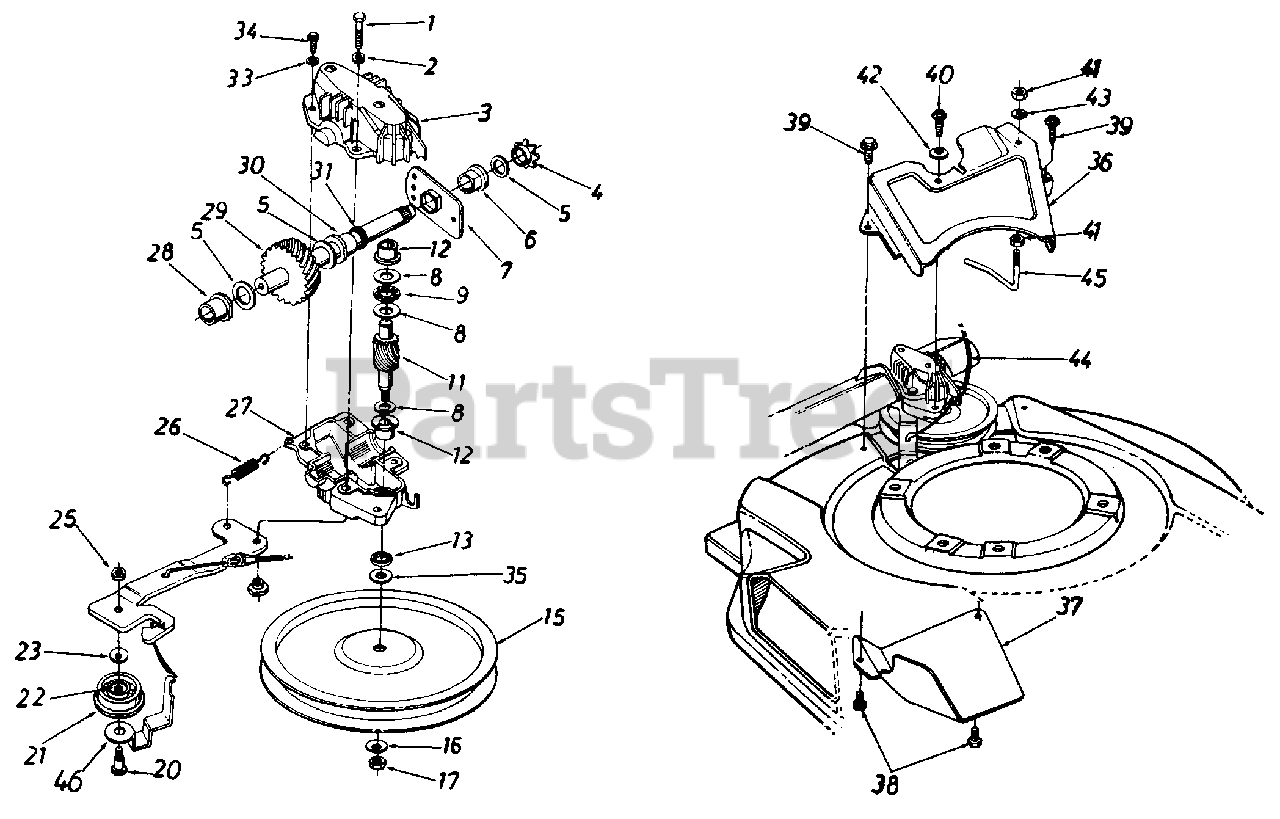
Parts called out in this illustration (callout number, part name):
1	Hex Bolt 1/4-20 x 1.25" Lg.
2	L-Wash. 1/4" I.D.
3	Upper Hsg. Half
4	#48 Sprocket 7 Tooth x 1/2 Pitch
5	Fl-Wash. 5/8" I.D. x .030
6	Hex Flange Brg. .631" I.D.
8	Thrust Wash. .382" I.D. x .70" O.D.
9	Thrust Bearing .375" I.D. x .812" O.D.
11	11 Tooth Helical Gear
12	Flange Bearing
13	Oil Seal
15	Fl-Pulley 5.06" I.D.
16	Bell-Wash. .265" I.D. x .75"
17	Hex Nut 1/4-28 L.H. Thd.
20	Shld. Bolt .375" Dia. x .40"
21	Fl-Idler Plastic 1.50" Dia.
22	Needle Brg. .375" x .375"
23	Bell-Wash. .265" I.D. x .75"
25	Hex Patch L-Nut 1/4-28 Thd.
26	Extension Spring 1.12" Lg.
27	Lower Hsg. Half
28	Flange Bearing .56 Dia.
29	Shaft Ass'y.
30	Flange Bearing .629 Dia.
31	Oil Seal .625 Dia.
33	L-Wash. #10 I.D.
34	Hex B-Tap Scr. #10 x .62"
35	Hex Washer .26" x .88"
39	Hex AB-Tap Scr. 1/4 x .50" Lg.
40	Hex B-Tap Scr. 1/4 x .62" Lg.
41	Hex Nut 1/4-20 Thd.
42	Bell-Wash. .265" I.D. x .75"
43	L-Wash. 1/4" I.D.
44	S.P. Cable--48" Lg.
45	S.P. Belt Guard
46	Belt Guard
